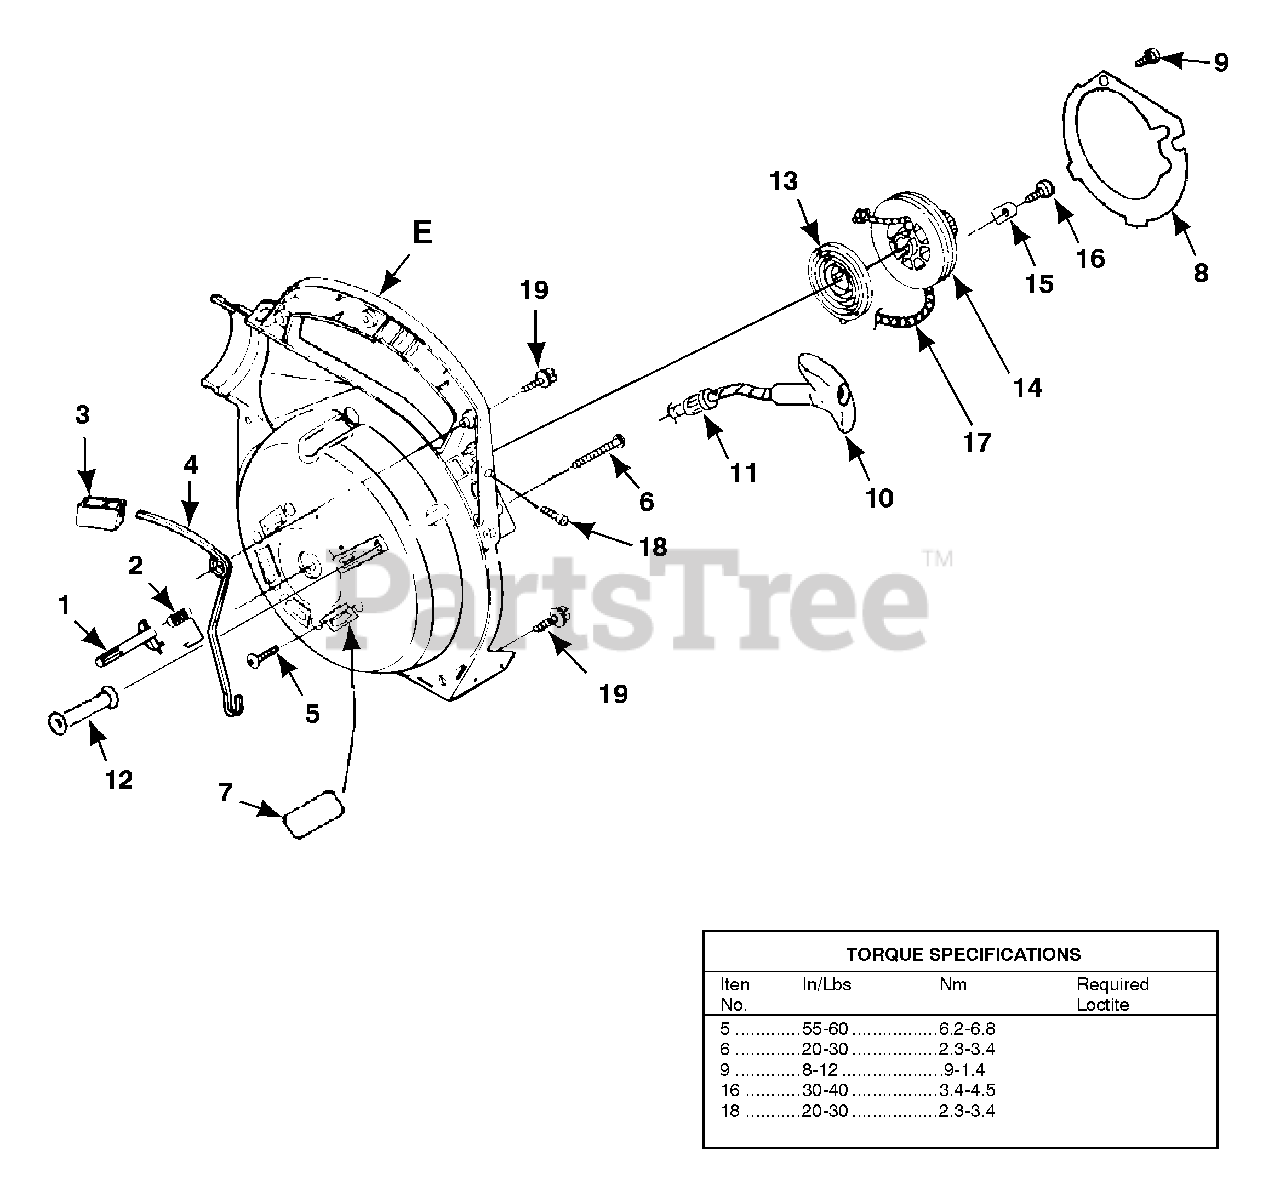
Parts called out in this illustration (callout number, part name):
1	LATCH-Throttle
2	SPRING-Throttle Latch
3	TRIGGER-Throttle
4	LEVER-Throttle
5	SCREW-Thread Form. (10-24 X 3/4")
6	SCREW-Thread Form. (#10 X 1 5/8")
7	KIT-Sealing
8	PLATE-Rotor
9	SCREW-Thread Form. (#6 X 1 3/8")
10	GRIP-Starter
11	BUSHING-Starter
12	GUIDE-Starter Rope
13	SPRING & CONTAINER
14	PULLEY-Starter
15	BRACKET-Retaining
16	SCREW-Thread Form. (#10 X 1/2")
17	ROPE-Starter
18	SCREW-Phil. Hd. (8-32 X 5/8")
E	VOLUTE HOUSING & STARTER
